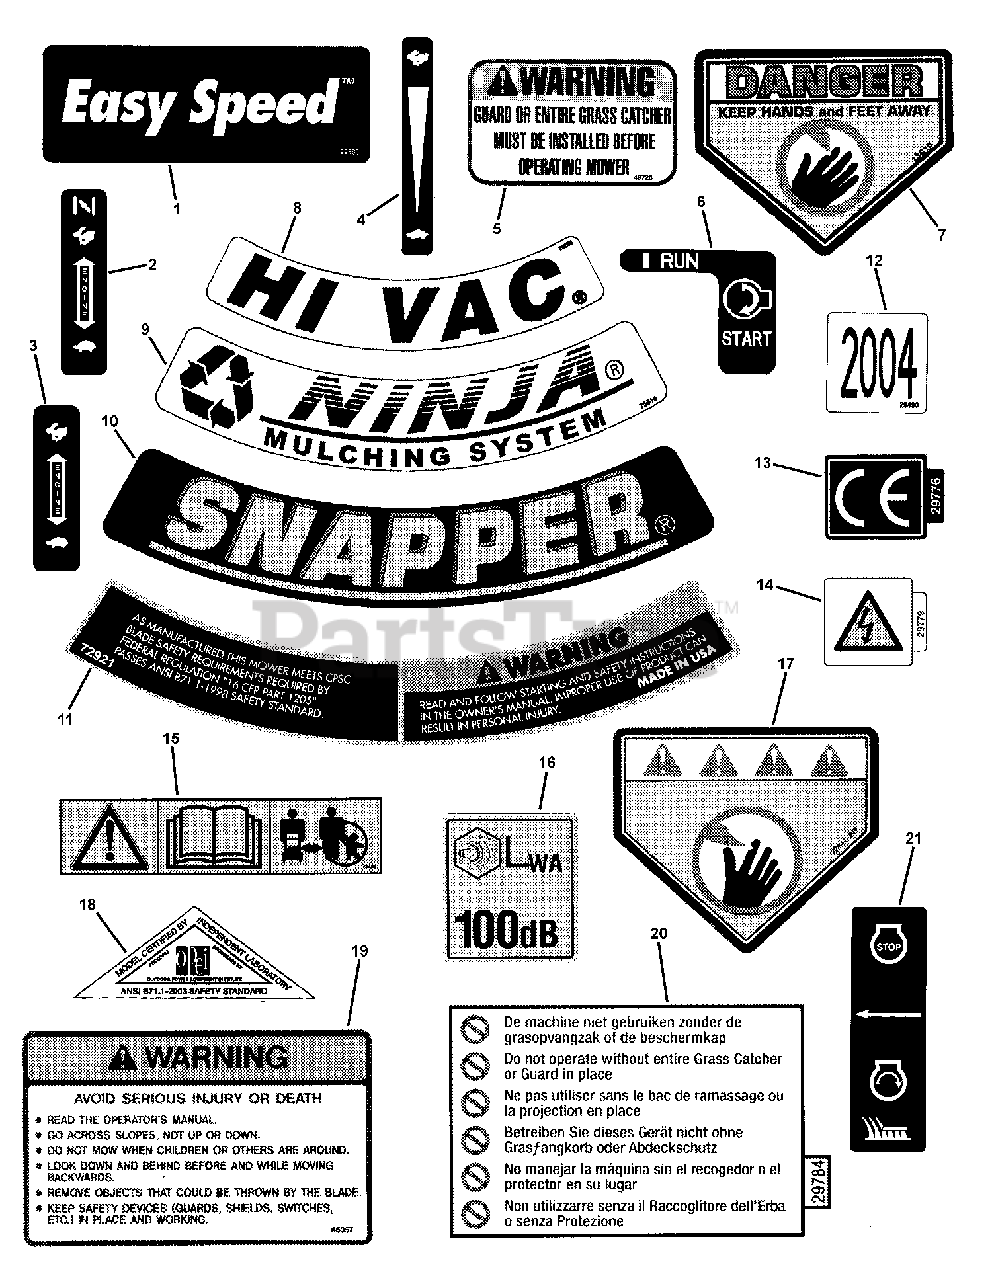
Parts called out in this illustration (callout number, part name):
1	DECAL, Easy Walk
2	DECAL, Throttle Control, KWV
3	DECAL, Throttle Control, B&S
4	DECAL, Speed Shift
5	DECAL, Chute/Deflector
6	DECAL, Ignition Switch
7	DECAL, Danger, Cut Finger
8	DECAL, Hi Vac
9	DECAL, Ninja
10	DECAL, Snapper
11	DECAL, Warning (Deck)
12	DECAL, 2004 Year of Mfg.
13	DECAL,Euro Community (CE)
14	DECAL, Spart Plug International Symbol
15	DECAL, Caution, Symbols
16	DECAL, Noise (European)
17	DECAL, Warning (Euro)
18	DECAL, OPEI Walk/Ride
19	DECAL, Warning
20	DECAL, Deck/Chute International Warning
21	DECAL, OPC Bail (International Symbol)
